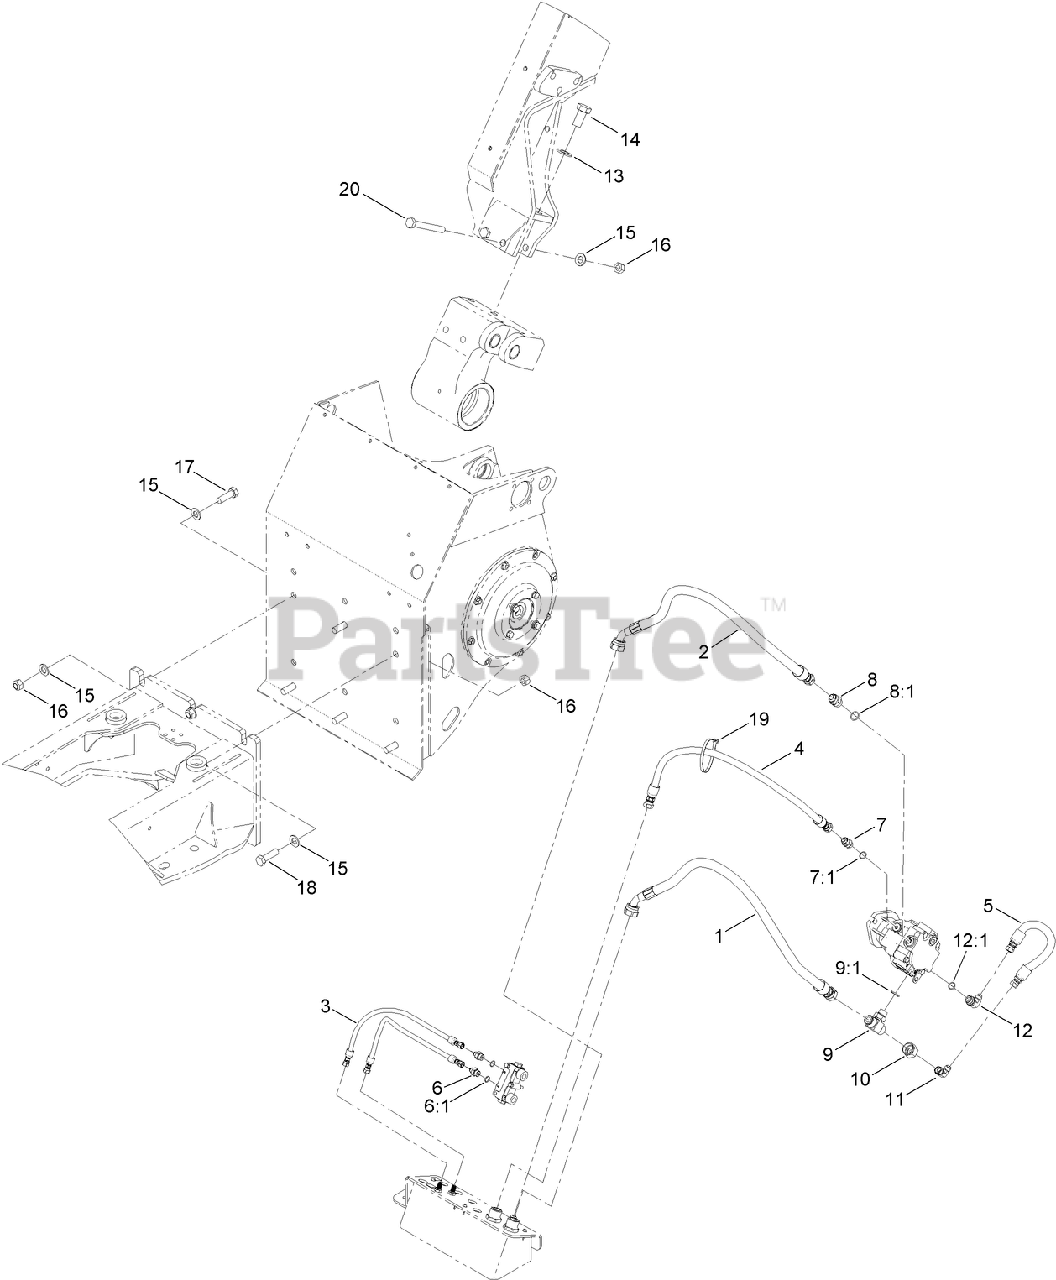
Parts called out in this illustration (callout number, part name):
1	HOSE ASM
2	HOSE ASM
3	HOSE ASM HYD
4	HOSE ASM
5	HOSE ASM
6	CONNECTOR
6:1	O-RING
7	FITTING-STRAIGHT
7:1	O-RING
8	FITTING-STRAIGHT
8:1	O-RING
9	FITTING-TEE
9:1	O-RING
10	FITTING-Restrictor
11	FITTING-ELBOW, 90
12	FITTING-90 DEG
12:1	O-RING
15	WASHER-Flat
16	NUT-LOCK
17	SCREW-HH
19	TIE-CABLE
20	SCREW-HH
